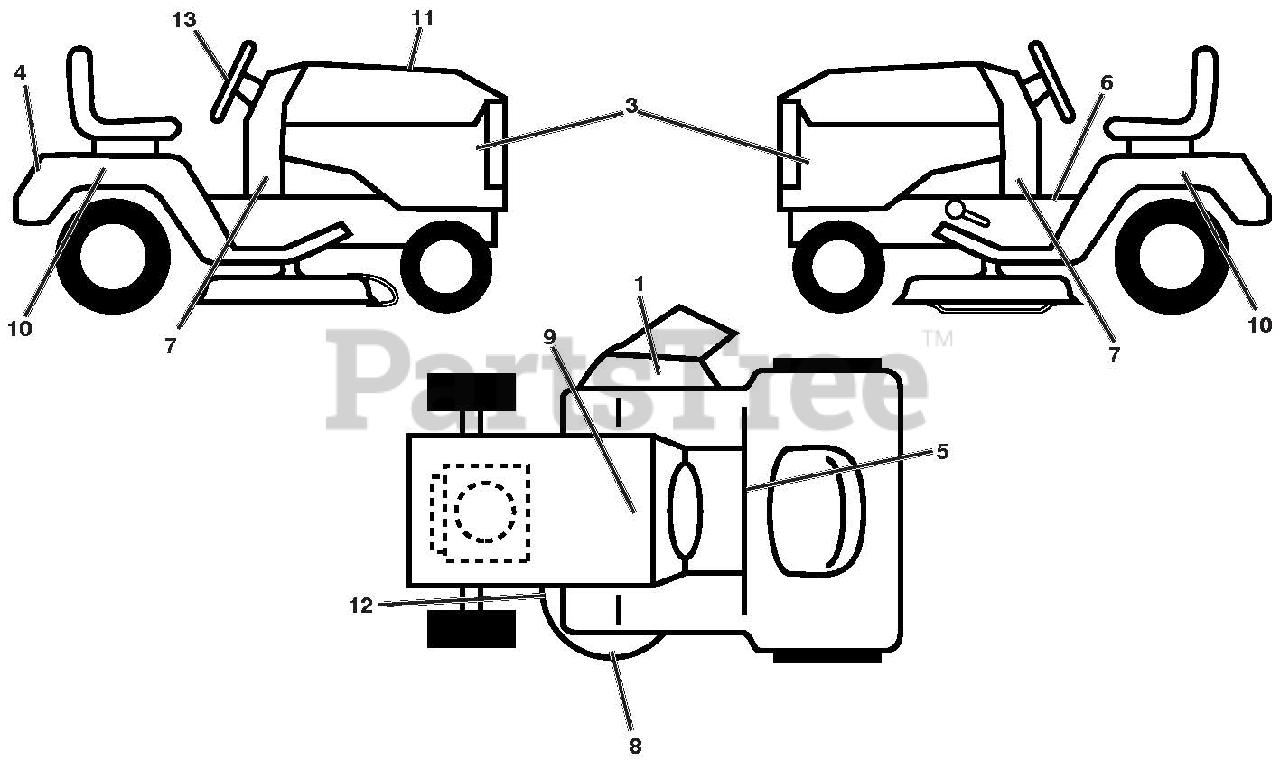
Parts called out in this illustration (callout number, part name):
1	DECAL DECK/DEFLECT. WARNING
3	DECAL.SDPNL.PWRDBY KOHL.ARIENS
4	DECAL.FENDER.REAR.ARIENS
5	DECAL.FENDER
6	DECAL, FENDER WARNING
7	DECAL LOWER DASH
8	DECAL MOWER CAUTION
9	DECAL.BAT.DAN/POI P/L SYM.WPN
10	DECAL FENDER SIDE
11	DECAL REPLACEMENT
12	DECAL.MOWER.SCH
13	DECAL.WHEEL.STEER.ARIENS
